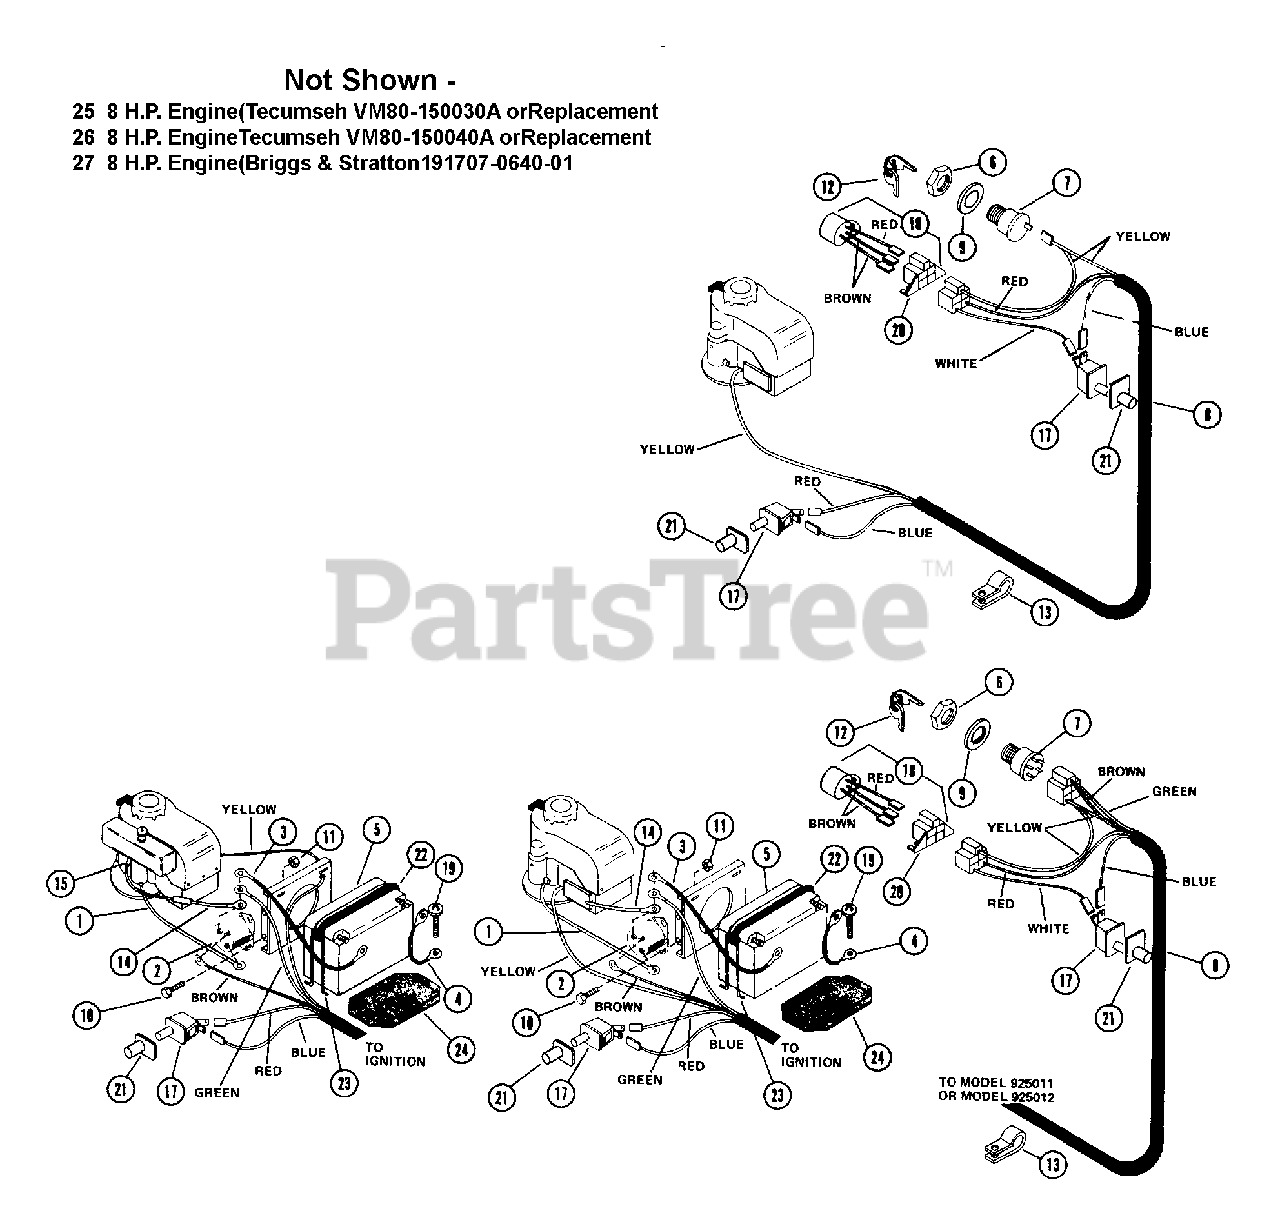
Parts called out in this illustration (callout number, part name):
1	GROUND CABLE
1	GROUND CABLE .25X13.00X.31
2	SOLENOID,STARTER SWITCH
3	GROUND CABLE
4	GROUND WIRE
5	BATTERY
6	NUT .625-32 ALUM
7	IGNITION SWITCH ASSEMBLY
7	KEY SWITCH ASSEMBLY
8	WIRING HARNESS
9	WSHR-LK-INT .625X.045 PL
10	BLT-HEX .25-20X.50 PL GR2
11	NUT-LK-CTR .250-20 PL
12	KEYS
13	CLIP
14	CHARGING WIRE
15	FUSE
18	MODULE ASSEMBLY
19	SCR-TAP 10-24X.375 CRPH 1A
20	CONNECTOR
21	SCR-TAP 12-24X.50 HWH PL TR
22	BATTERY STRAP
23	HOOK
24	RUBBER PAD
25	8 H.P. Engine(Tecumseh VM80-150030A orReplacement)
26	8 H.P. Engine(Tecumseh VM80-150040A orReplacement)
27	8 H.P. Engine(Briggs & Stratton191707-0640-01 or Replacement)
